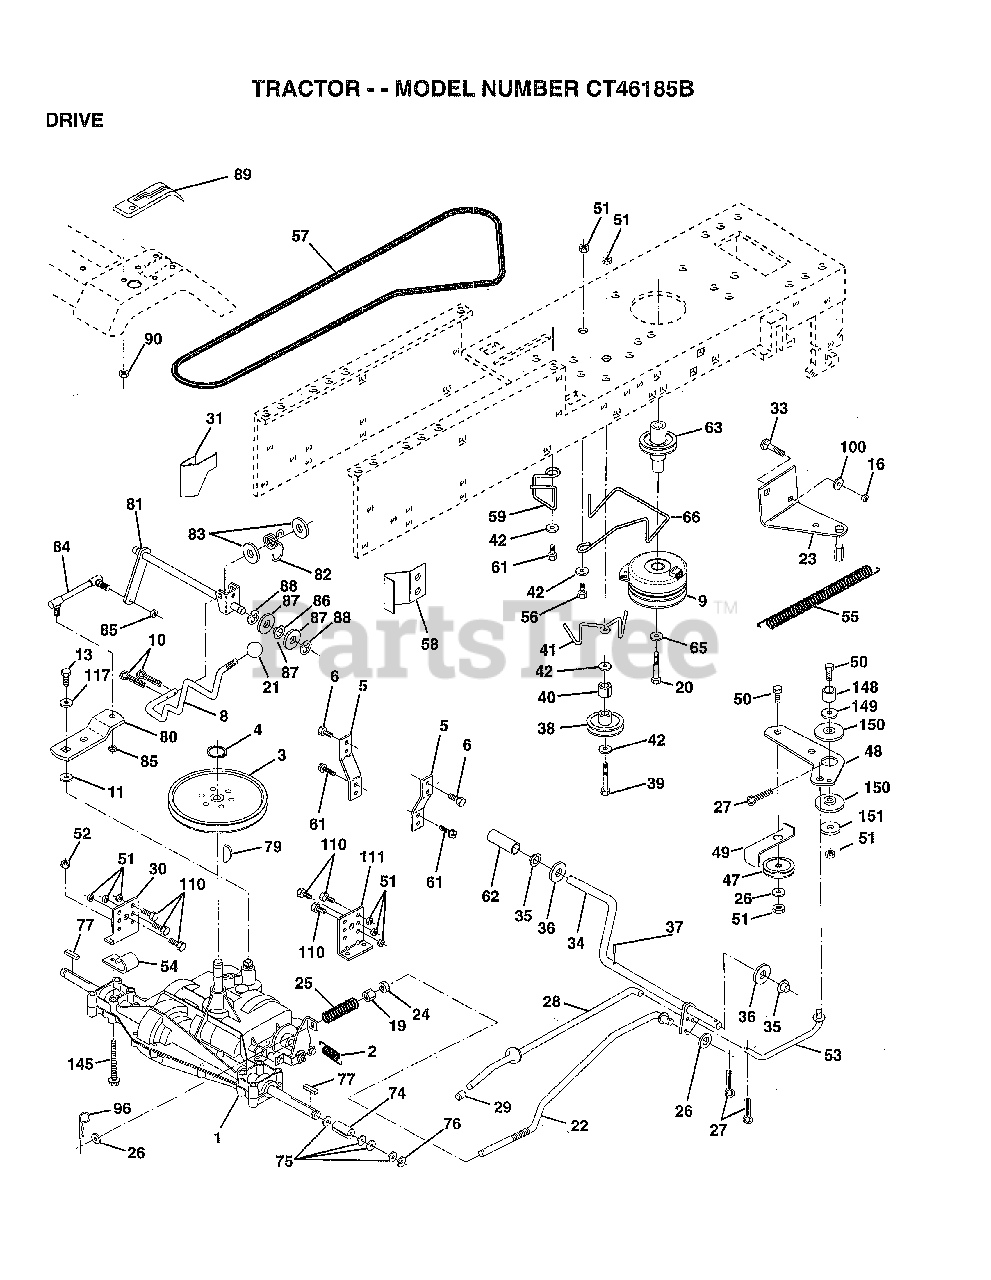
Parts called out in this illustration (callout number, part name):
3	PULLEY TRANSAXLE
4	RING
5	STRAP TORQUE
6	SCREW
8	ROD SHIFT FEND YT
9	CLUTCH.ELECTRIC
10	PIN COTTER 1/8
11	WASH-SHFT PLT LT
13	BOLT.1/4-28.W/PAT
19	NUT
20	BOLT.7/16-20X4.25
21	KNOB T (1/2-HOLE)
22	ROD.ASM.BK.44.MWR
23	BRACKET.CLUT.MTG.
24	NUT
25	"SPRING,ROD BRAKE"
26	WASHER
27	COTTER PIN
28	ROD.BRAKE.PARK.LT
29	PLUNGER CAP T
30	BRKT TRANS LH
31	KEEPER BELT LH
33	BOLT
34	SHAFT ASM-PEDAL F
35	NYLON BEARING
36	WASHER LT
38	PULLEY.IDLER.FLAT
39	BOLT
40	SPACER T
42	WASHER
48	BELLCRANK.CLUTCH
49	RETAIN BELT
53	"LINK, CLUTCH T"
54	"CLIP,INSULATOR"
55	"SPRING, RETURN LT"
56	V-BELT.DRIVE
57	HOUSING ASSEMBLY
58	"KEEPER,BELT RH"
59	KEEPER BELT CNTSP
61	SCREW
62	PEDAL COVER T
63	PULLEY.CLUTCH.EVX
65	LOCKWASHER
66	KEEPER-BELT
74	SPACER HYT
75	WASHER
76	E RING HYT
77	SQ KEY STD
80	"ARM,SHIFT"
81	SHAFT ASM CROSS
82	"SPRING,TORSION"
83	WASHER
84	"ROD LINK,SHIFT AD"
85	NUT.CNT.LOCK.1/4
86	BUSHING
87	WASHER D
88	KLIP RING
89	CONSOLE SHIFTER
90	NUT
96	RETAINER M
100	WASHER M
111	BRKT TRANS RH
117	WASHER PM
145	BOLT.HEX.FLGHD
149	SPACER RETAINER
150	BUSHING.NYLON
151	WASHER
